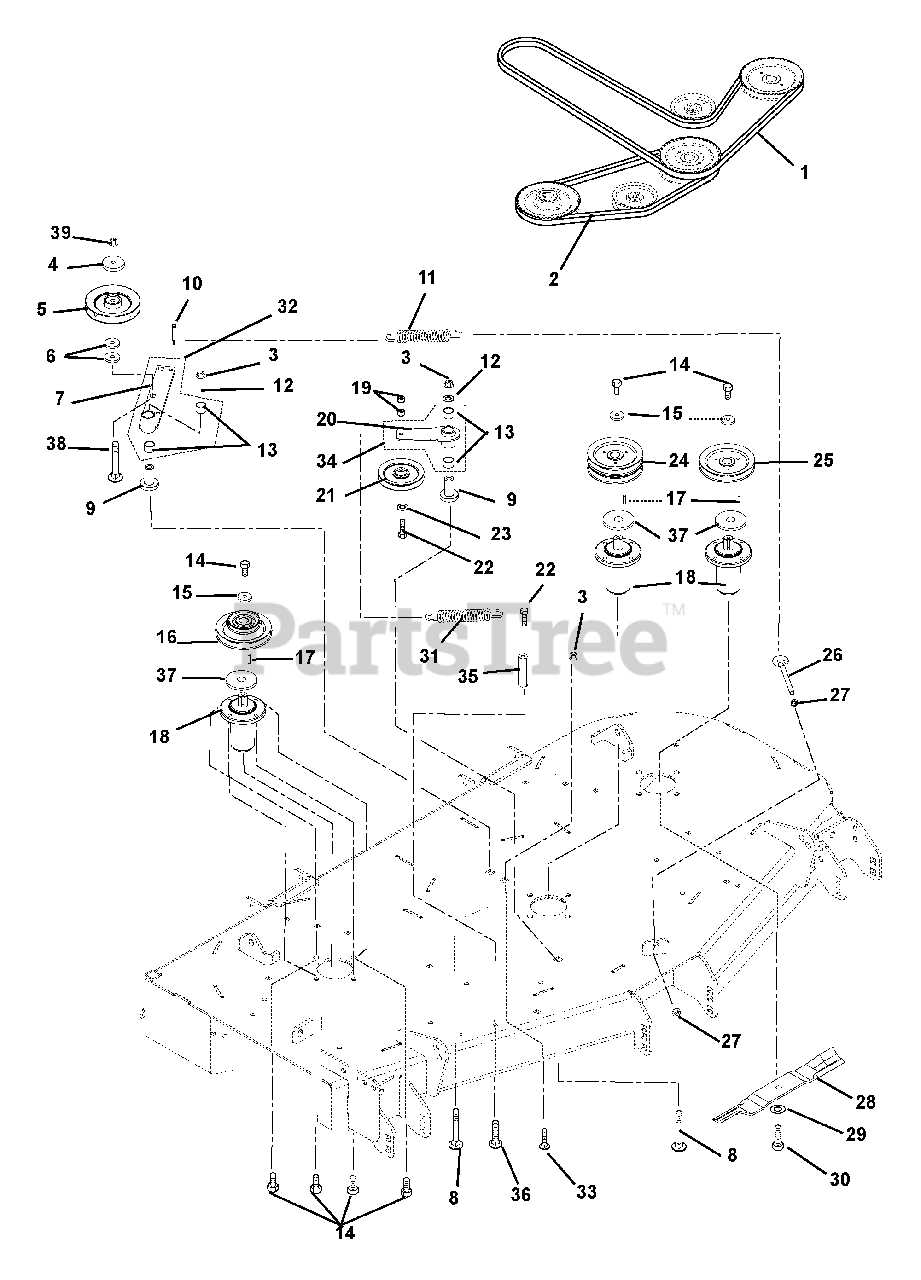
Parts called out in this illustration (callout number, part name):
1	Belt, 120.50" Long, PTO Drive Hex
1	Belt, 130" Long, PTO Drive Hex
1	Belt, 147" Long, PTO Drive Hex
2	V-Belt, 56" Long Cog B-Section
2	V-Belt, 63" Long Cog B-Section
2	V-Belt, 76" Long Cog B-Section
3	Nut, .50-13 Nyloc Flange
4	Cap, Idler Bearing Sealing
5	Pulley, V 6.0 x .500 ID DBL. Bearing
6	Washer, Flat Stee,l .515 x 1.625 x .250
7	Idler, Pivot Arm
8	Bolt, Round Head Square Neck .50-13 x 3.50
9	Bearing, Pedestal
10	Bolt, Shoulder .38-16 x .30 Hex
11	Spring, Extension)
12	Washer, Flat Steel .531x 1.250 x.100
13	Bearing, 1.00 x 1.12 x .75
14	Bolt, Hex .38-16 x 1.00
15	Washer, Flat Steel .406 x 1.50 x .245
16	Sheave, Double, 1" ID x 6" OD and 3.50" OD
16	Sheave, Double, 1" ID x 6.75" x 4.35" OD
16	Sheave, Double, 1" ID x 8.25" and 5.25" OD
17	Key, Square .25 x .25 x 1 RC 40-50
18	Spindle Assembly
19	Nut, Locking-Center .38-16
20	Idler, Pivot Arm
21	Sheave, .38" ID x 5" OD
22	Bolt, Hex .38-16 x 2.25
23	Washer, Flat Steel .406 x .812 x .065
24	Sheave, Double 1" ID x 6.00" OD
24	Sheave, Double 1" ID x 6.75" OD
24	Sheave, Double 1" ID x 8.25" OD
25	Sheave, Single 1" ID x 6.00" OD
25	Sheave, Single 1" ID x 6.75" OD
25	Sheave, Single 1" ID x 8.25" OD
26	Bolt, .38-16 x 4.50 .62 Diameter Eye
27	Nut, Hex, Jam .375-16
28	Blade, 18.00" Mower
28	Blade, Mower (20.50")
28	Blade, Mower (24.50") without Tungsten Carbide Hardfacing
29	Washer, Bellville .63 x 1.625 x.14
30	Bolt, Hex .62-18 x 1.75 Grade 8
31	Spring, Extension
32	Assembly, PTO Idler Pivot Arm
33	Bolt, Round Head Square Neck .50-13 x 1.5, Full Thread, Grade 5
34	Assembly, Idler Pivot Arm
35	Nut, Coupling .375-16 x 1.75
36	Bolt, Round Head Square Neck .38-16 x 1.00
37	Retainer, Grease
38	Bolt, Round Head Square Neck .50-13 x 3.00 Grade 5
39	Nut, Locking Center .50-13
